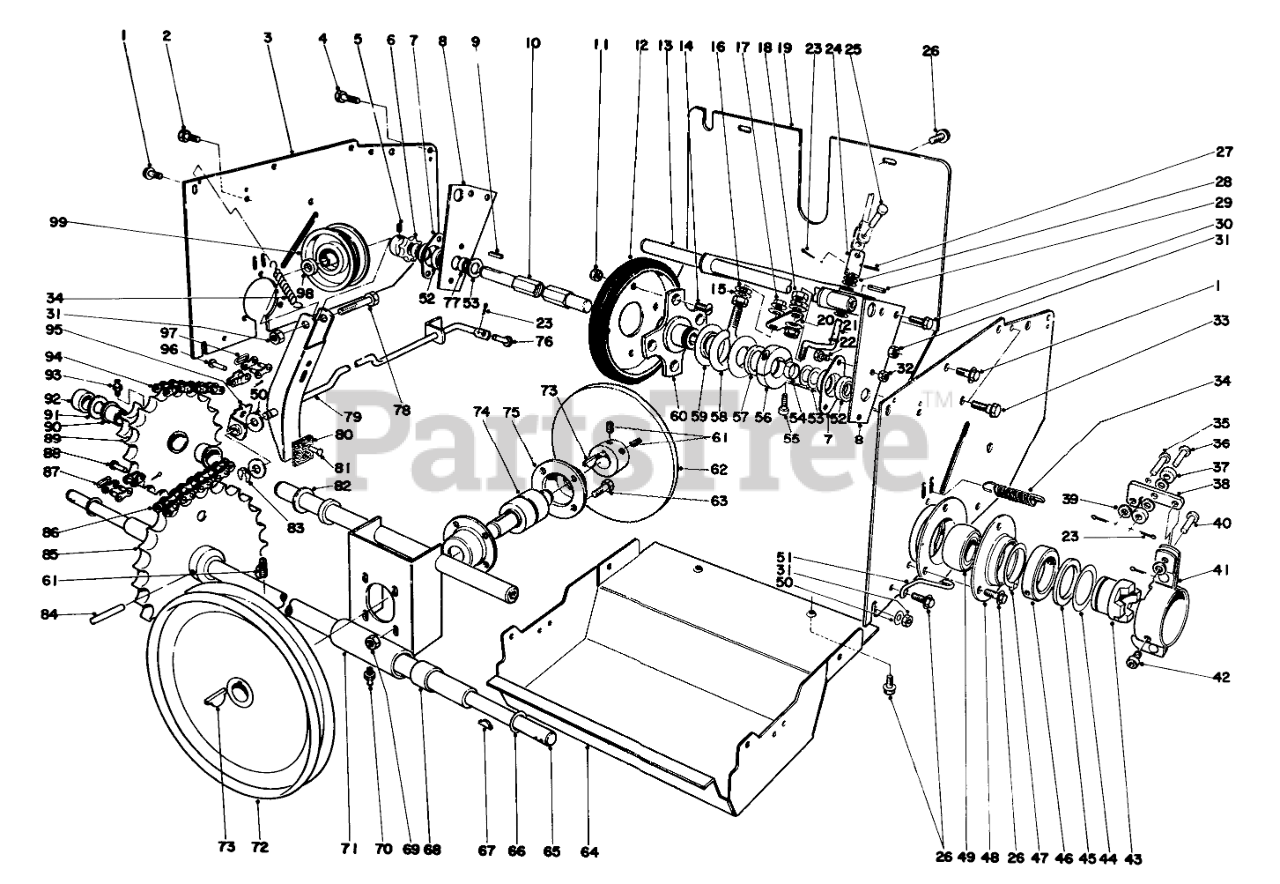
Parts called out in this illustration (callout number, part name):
1	SCREW-HHF
2	SCREW-HWH,THD ROLL
3	Side Plate Drive
4	SCREW-HH, TAP
5	SCREW-HSH
6	SPROCKET
7	BEARING CUP
8	Mount Hex Shaft
10	FRICTION WHEEL SHAFT
11	Nut
12	Disc
13	Bracket Dead Shaft
14	5/16-18X5/8 FLT HD MS
15	Washer
16	WASHER-SPRING
17	NUT-LOCK, FLANGE
18	Nut
19	REAR COVER R
20	SHIFT ROD PIVOT
21	CONNECTION ROD
22	SCREW-HH
23	PIN-COTTER
24	U JOINT TUBE
25	CLEVIS PIN
26	SCREW-HWH
27	PIN-SPRING
28	Spacer
29	PIN-ROLL
30	SCREW-HWHTF
31	NUT-HEX
32	NUT-LOCK
33	SHOULDER SCREW
34	EXTENSION SPRING
35	PIN-CLEVIS
36	PIN-CLEVIS
37	CLUTCH ROLLER
38	CLUTCH CAM ARM
39	WASHER-FLAT
40	PIN-CLEVIS
41	CLUTCH MT BRKT ASM
42	Hex Socket Capscrew
43	Clutch Wheel
44	THRUST WASHER
45	THRUST BEARING
46	CLUTCH MOUNT COLLAR
47	RING-RETAINING, EXTERNAL
48	BEARING FLANGE
49	BEARING
50	WASHER-FLAT
51	Clutch Retainer
52	BEARING
53	WASHER-FLAT
54	SPLIT SPACER
55	SCREW-HSH
56	Collar
57	WASHER-THRUST
58	SLIDER RING COLLAR
59	SLIDER RING
60	TRACTION DISC HUB
61	SCREW-SET, SQH
62	Friction Plate
63	SCREW-HH
64	LOWER SHIELD R
65	Axle Shaft
66	WASHER
67	1/4X1-1/16 HI-PRO KEY
68	BUSHING
69	NUT-KEPS
70	FITTING-GREASE
71	Bulkhead (Incl. Ref. #68)
72	Pulley
73	KEY-WOODRUFF
74	BEARING-FRICTION PLATE
75	HOUSING BEARING
76	PIN-CLEVIS
77	SPACER
78	SCREW-HH
79	Auger Idler & Brake(Incl. Ref. #80-81)
80	BRAKE PAD
81	.185 DIA X .375 RT +
82	THRUST WASHER
83	Klip Ring
84	PIN-GROOVE
85	Lower Sprocket
86	ROLLER CHAIN
87	LINK-CHAIN
88	LINK-OFFSET
89	Upper Sprocket(Incl.Ref. #90&93)
90	3/4ID X 3/4LG BSHG
91	WASHER-THRUST
92	SPACER-IDLER
93	FITTING-GREASE
94	1/4 X 42 CHAIN W/LINK
95	Bracket-Clutch
96	1/4 OFFSET LINK
97	LINK-CONNECTING
98	Spacer
99	PULLEY-IDLER
